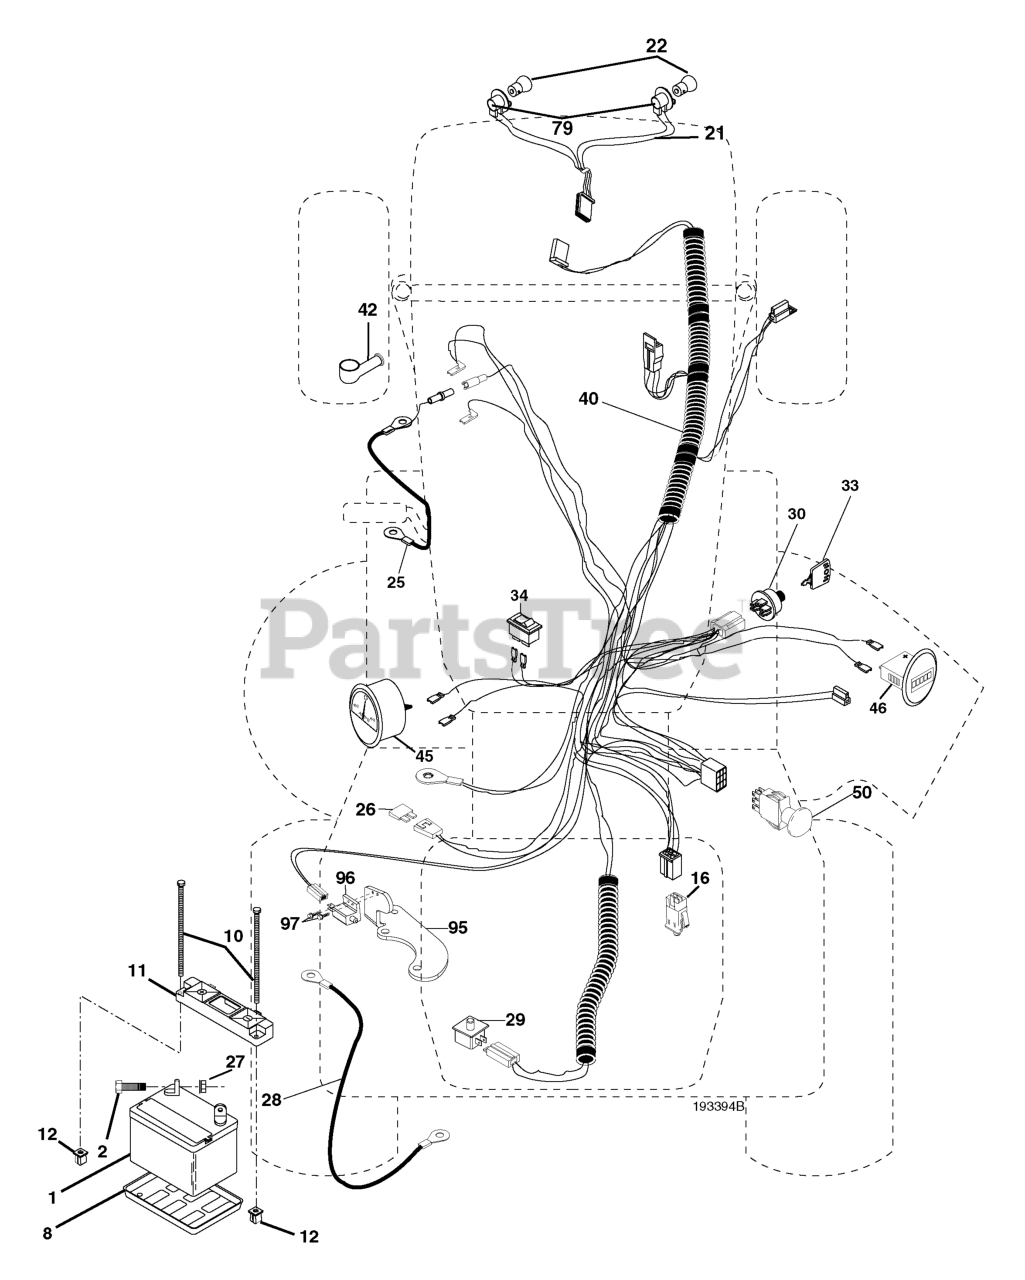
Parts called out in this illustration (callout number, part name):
1	BATTERY 12V .35 AMP
2	BOLT.HEX.1/4.X.3/4.DICHROMATE
8	BATTERY TRAY T
10	BOLT 1/4-20 X 7.5
11	BATTERY HOLDDOWN FRONT MOUNT
12	NUT, PUSH NYLON 1/4" BATTERY
16	SWITCH INTERLOOK PUSH-IN
21	HARNESS.W/LIGHT SOCKET
25	CABLE.4GA.RED.W/16GA.RED.WIRE
27	NUT
28	CABLE, GROUND
29	SWITCH.SEAT.DP W/RAMPS
30	SWITCH.IGN.DELTA.W.LGH.ROS
33	KEY MLD GEN DELTA
40	HARNESS. IGN.VGT.RHD
42	COVER.TERMINAL.RED
45	RP AMMETER.ROUND.SILVER.DELTA
46	RP HOURMETER SNAP-IN
50	RP.PTO.SWITCH.8 TERMINAL.BLACK
79	BULB HOLDER ASM.
92	HARNESS.PIGTAIL.REVERSE.SWITCH
93	SCREW.PLASTITE
94	MODULE.REVERSE.ROS
